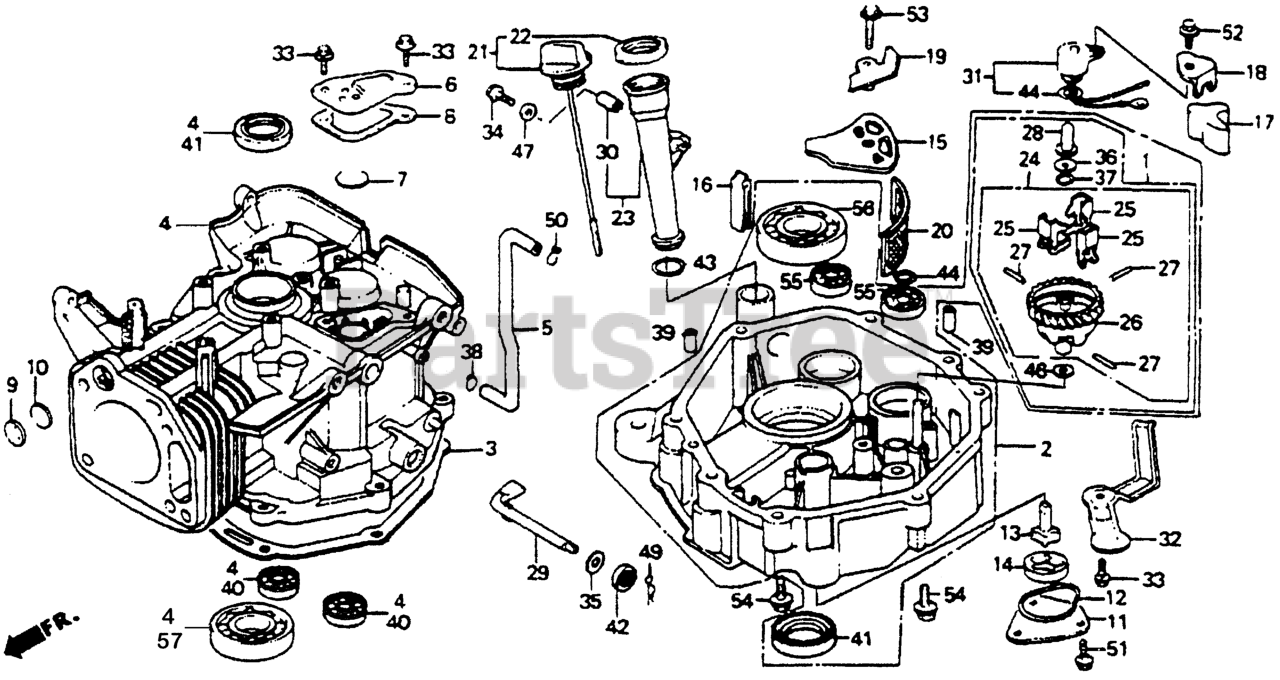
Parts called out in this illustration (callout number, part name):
1	GOVERNOR KIT Use from Engine SN 2086153.
1	GOVERNOR KIT Use up to Engine SN 2086152.
2	PAN ASSY., OIL
3	GASKET, OIL PAN
4	CYLINDER ASSY.
5	TUBE, BREATHER
6	CAP, BREATHER CHAMBER
7	VALVE, BREATHER
8	GASKET, BREATHER CAP
9	PLATE, ONE-WAY VALVE
10	VALVE, ONE-WAY
11	COVER, OIL PUMP
12	O-RING, PUMP COVER
13	ROTOR (INNER)
14	ROTOR, OIL PUMP (OUTER)
15	PLATE, OIL FILTER
16	RUBBER, OIL RETURN
17	STOPPER, OIL
18	PLATE, OIL STOPPER
19	PLATE, SUCTION
20	SCREEN, OIL FILTER
21	CAP ASSY., OIL FILLER
22	GASKET, OIL FILLER CAP
23	EXTENSION, OIL FILLER
24	GOVERNOR ASSY.
25	WEIGHT, GOVERNOR
26	HOLDER, GOVERNOR WEIGHT
27	PIN, GOVERNOR WEIGHT
28	SLIDER, GOVERNOR
29	SHAFT, GOVERNOR ARM
30	COLLAR, EXTENSION Use up to Engine SN 1257294.
31	SWITCH COMP., OIL LEVEL
32	PROTECTOR, SWITCH
33	BOLT, FLANGE (6X12) (CT200)
34	BOLT, FLANGE (6X35)
35	WASHER, THRUST (8.1MM)
36	WASHER (6X16)
37	CLIP, GOVERNOR HOLDER
38	CLIP, TUBE
39	PIN, DOWEL (8X12)
40	BEARING, RADIAL BALL (6202)
41	OIL SEAL (35X52X8)
42	OIL SEAL (8X14X5)
43	O-RING (22.5X2.2) Use from Engine SN 1257295.
44	O-RING (11.8X2.4)
45	BOLT, DRAIN PLUG (20MM)
46	WASHER, PLAIN (6MM)
47	WASHER, PLAIN (6MM)
48	WASHER, DRAIN PLUG (20MM)
49	PIN, LOCK (8MM)
50	CLIP, TUBE (C11)
51	BOLT, FLANGE (6X12) Use up to Engine SN 1543277.
52	BOLT, FLANGE (6X16) Use from Engine SN 2056820.
53	BOLT, FLANGE (6X25)
54	BOLT, FLANGE (8X40)
55	BEARING, RADIAL BALL (6202)
56	BEARING, RADIAL BALL (6207)
57	BEARING, RADIAL BALL (6207)
NI	FILTER, OIL
NI	FILTER, OIL (Honda Code 6836290). (SOLD INDIVIDUALLY)
